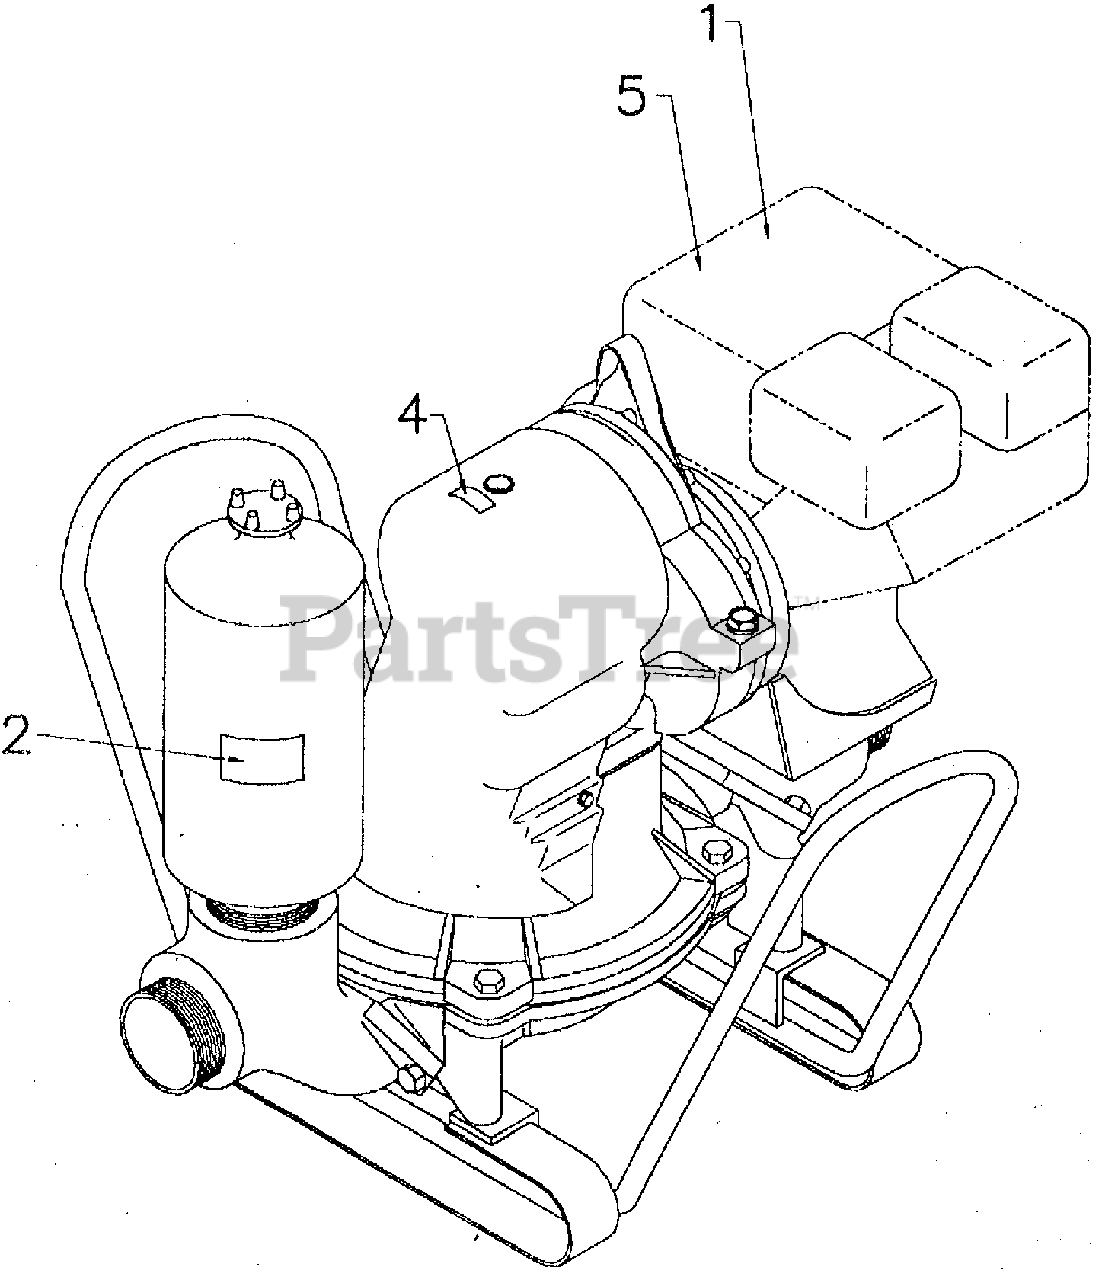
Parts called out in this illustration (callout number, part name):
1	MARK, OIL ALERT (ENGLISH)
2	LABEL, WARNING
4	DECAL, GREASE
5	MARK (WDP30X)
